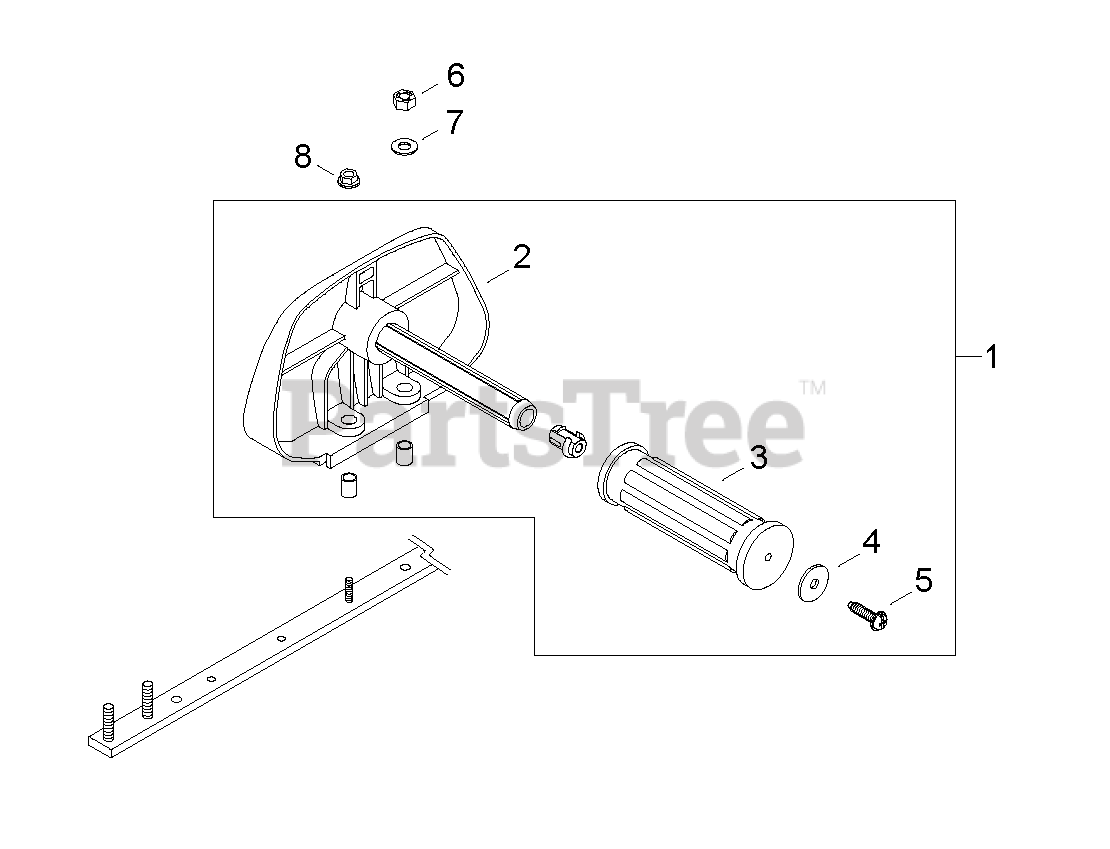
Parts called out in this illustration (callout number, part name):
1	HANDLE ASSY, FRONT
2	HANDLE, FRONT
4	WASHER 5 MM
5	SCREW 5×20
7	WASHER 6.5×13×1
8	NUT, FLANGE M5
